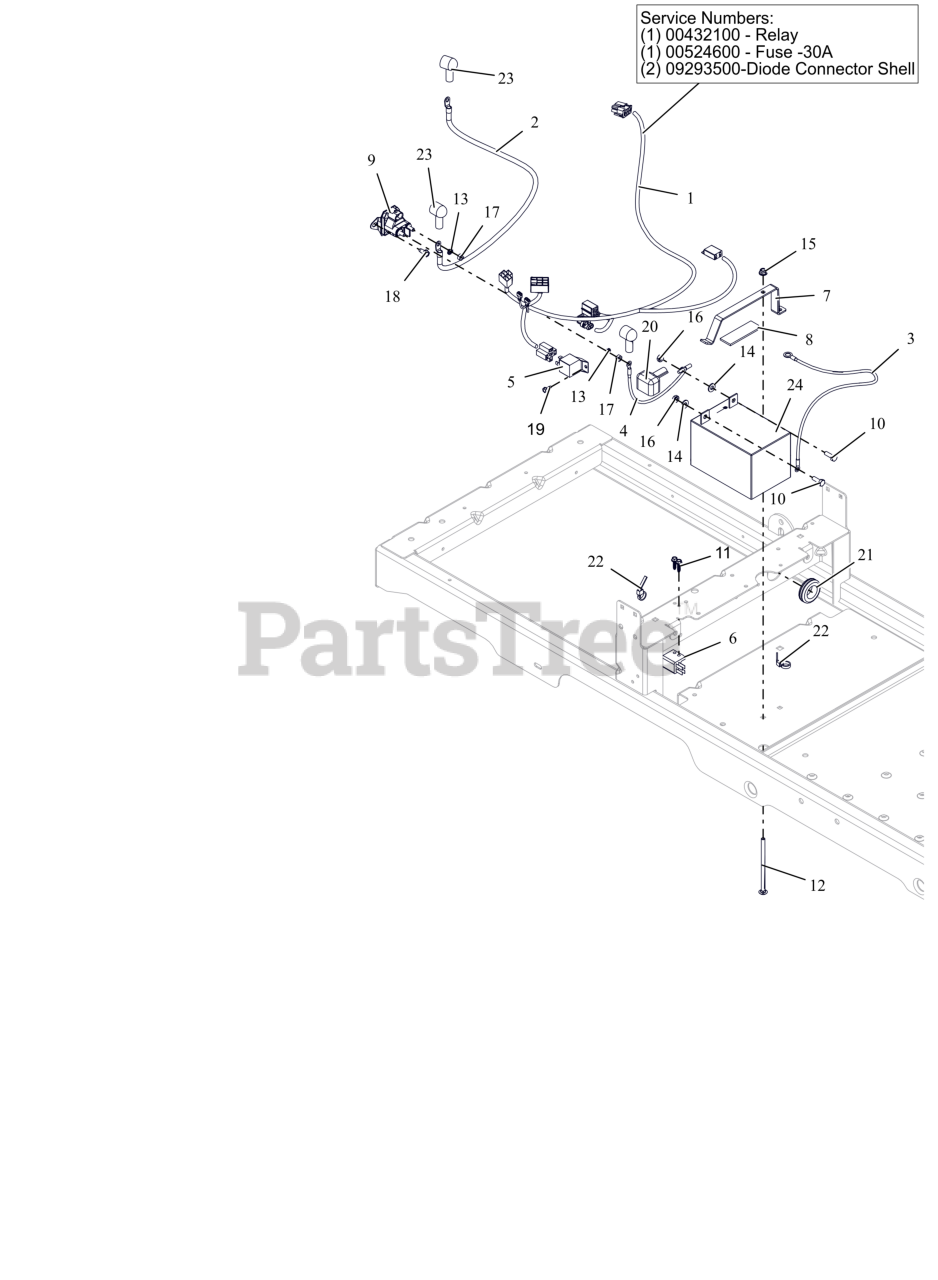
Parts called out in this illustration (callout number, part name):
1	HARNESS- EDGE/ZT WIRE
1	RELAY,SEALED W/DIODE
1	FUSE, 30 AMP.
1	DIODE, CONNECTOR SHELL
2	CABLE,POS W/(2)1/4 RING 21.5LG
3	CABLE, NEGATIVE 26" 6 GA.
4	CABLE,POS W/2 1/4 RING 15.0 LG
5	RELAY,SEALED W/DIODE
6	SWITCH- DOUBLE POLE N.O./N.O.
7	HOLDDOWN, BATTERY, U1&190CCA
8	PAD,RBR 1.0"X3.0" W/ADHESIVE
9	SOLENOID, STARTER (SEALED)
10	BLT, HEX .25-20X.75 G5 ZCC
11	SCR, PLASTITE-HWH 0.2 X 0.75 ZC120
12	BLT, RHSN .25-20X4.50 G5 ZCC
13	WSHR,LK-EXT.262X.502X.026 ZCC
14	WSHR,FLT .281X.625X.065 ZCC
15	NUT,NYL-FLG .25-20 GF ZCC
16	NUT-KEPS .250-20 ZCC
17	NUT-STD M6-1.0 ZCC
18	SCR-TAP .25-20X.50 HWH ZCC
19	@SCR-TAP 10-24X.50 HWH TR YWZC
20	INSULATOR
21	GROMMET 1.0ID X 1.38 OD
22	CABLE TIE LG 5-1/2
23	BOOT, EYELET TERMINAL
24	YUASA 895UR1 BATTERY
